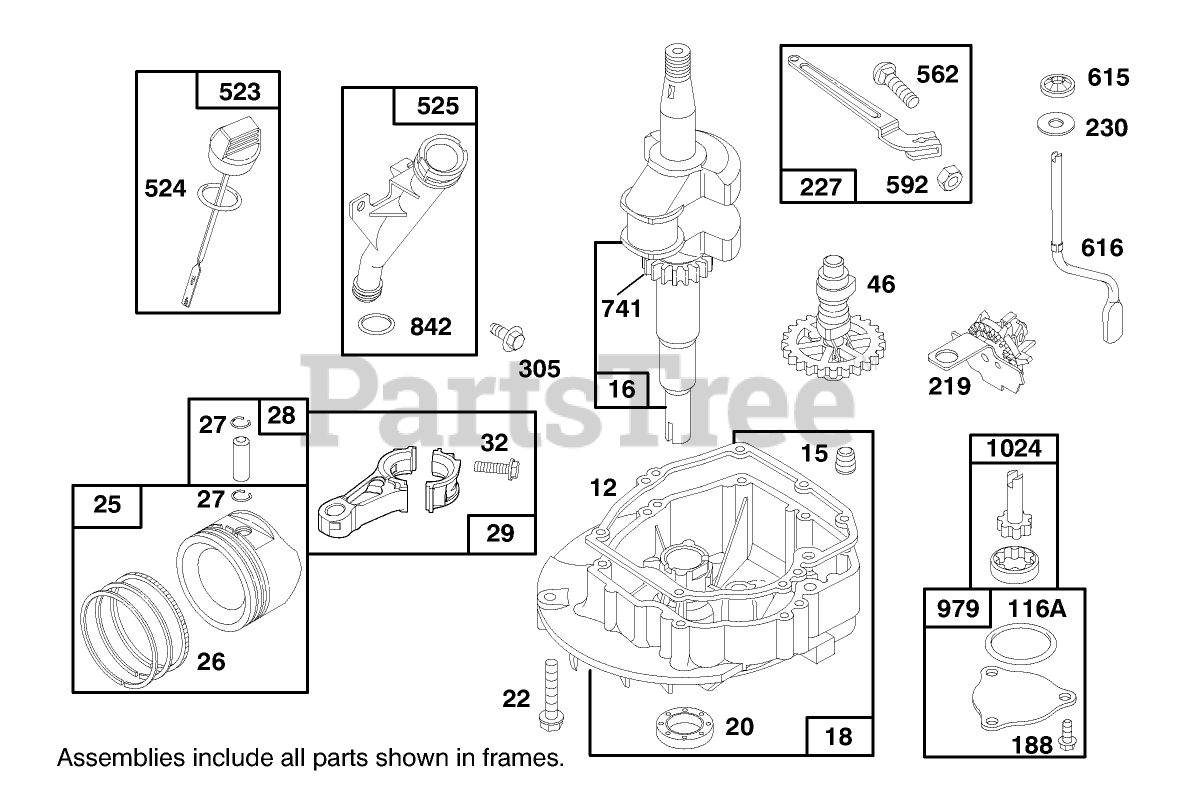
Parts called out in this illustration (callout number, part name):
12	ENGINE BASE GASKET
15	PIPE PLUG
20	SEAL-OIL
25	STD PISTON ASSEMBLY
27	PISTON PIN LOCK
28	PIN ASM - PISTON
29	CONNECTING ROD
116A	O RING SEAL
219	GOVERNOR/OIL SLINGER
227	GOVERNOR LEVER ASSEMBLY
305	SCREW - HEX HEAD
524	O-RING
562	GOVERNOR LEVER BOLT
592	HEX NUT
842	O-RING
979	OIL PUMP COVER
1024	OIL PUMP
